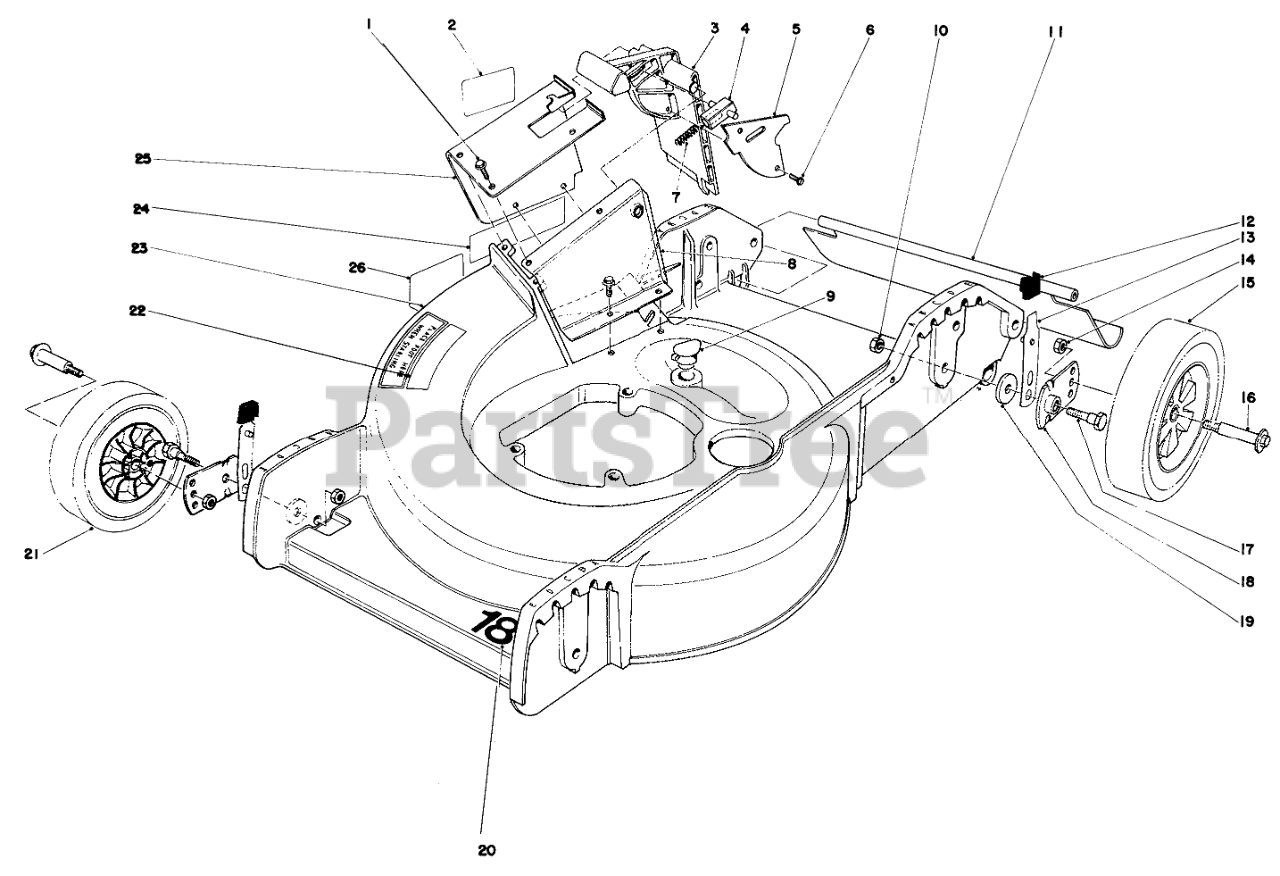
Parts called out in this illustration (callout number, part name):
1	SCREW
2	Decal Door
3	Door Mulching
4	Door Latch
5	Cover Door
7	SPRING-COMPRESSION, LATCH
8	Inner Tunnel
9	WASHOUT PLUG
10	Nut
11	SHIELD - TRAILING
12	KNOB-ARM
13	SPRING ARM ASM
14	Nut
15	WHEEL & TIRE ASM
16	BOLT-WHEEL
17	PIVOT SCREW
18	PIVOT ARM ASSY
19	PIVOT WASHER
20	Decal
21	Wheel & Tire Assembly
22	Decal Place Foot Here
23	Housing
24	Decal Door
25	Tunnel Outer
26	DECAL-DANGER
